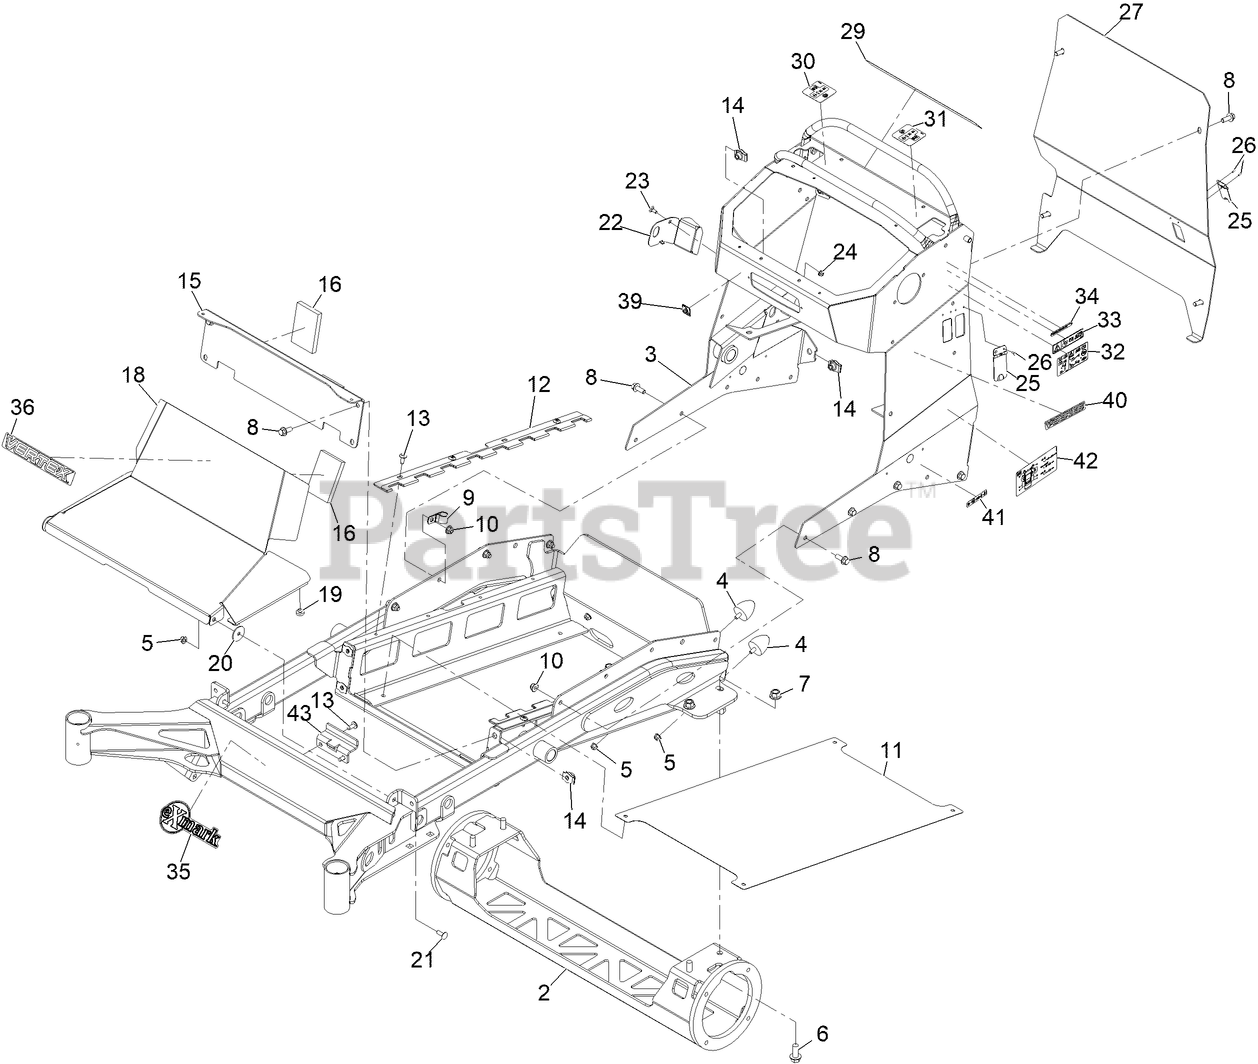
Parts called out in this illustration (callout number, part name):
2	Frame-Axle ASM [red]
3	TOWER ASM
4	BUMPER-RUBBER
5	NUT-HF, NI
6	SCREW-HHF
7	Nut-Lock 1/2-13
8	SCREW-HHF 3/8-16 X 1
9	CLAMP-R
10	NUT-HF, NI
11	PLATE-SKID
12	BRACKET-RETENTION, BATTERY
14	NUT-TINNERMAN
15	PLATE-BATTERY MNT
16	PAD-FOAM
18	COVER-MOTOR CONTROLLER
20	WASHER-NYLON
21	BOLT-CARR
22	PLATE-LATCH
23	SCREW-CARR
25	PLATE-COVER, SPRING
26	RIVET-POP
27	PLATE-COVER, PLATE
29	DECAL-WARNING
30	DECAL-OPC CONTROL, RIGHT
31	DECAL-OPC CONTROL, LEFT
32	DECAL-CHARGING PORT
33	DECAL-SERVICE, SHUT-OFF
34	DECAL-WARNING
35	DECAL, EXMARK LOGO
36	DECAL-VERTEX LOGO
39	DECAL-LIGHT, WARNING
40	Decal-V-Series
41	DECAL-TRANSMISSION FLUID
42	DECAL-SERVICE AID
43	Bracket-Cover Stop
